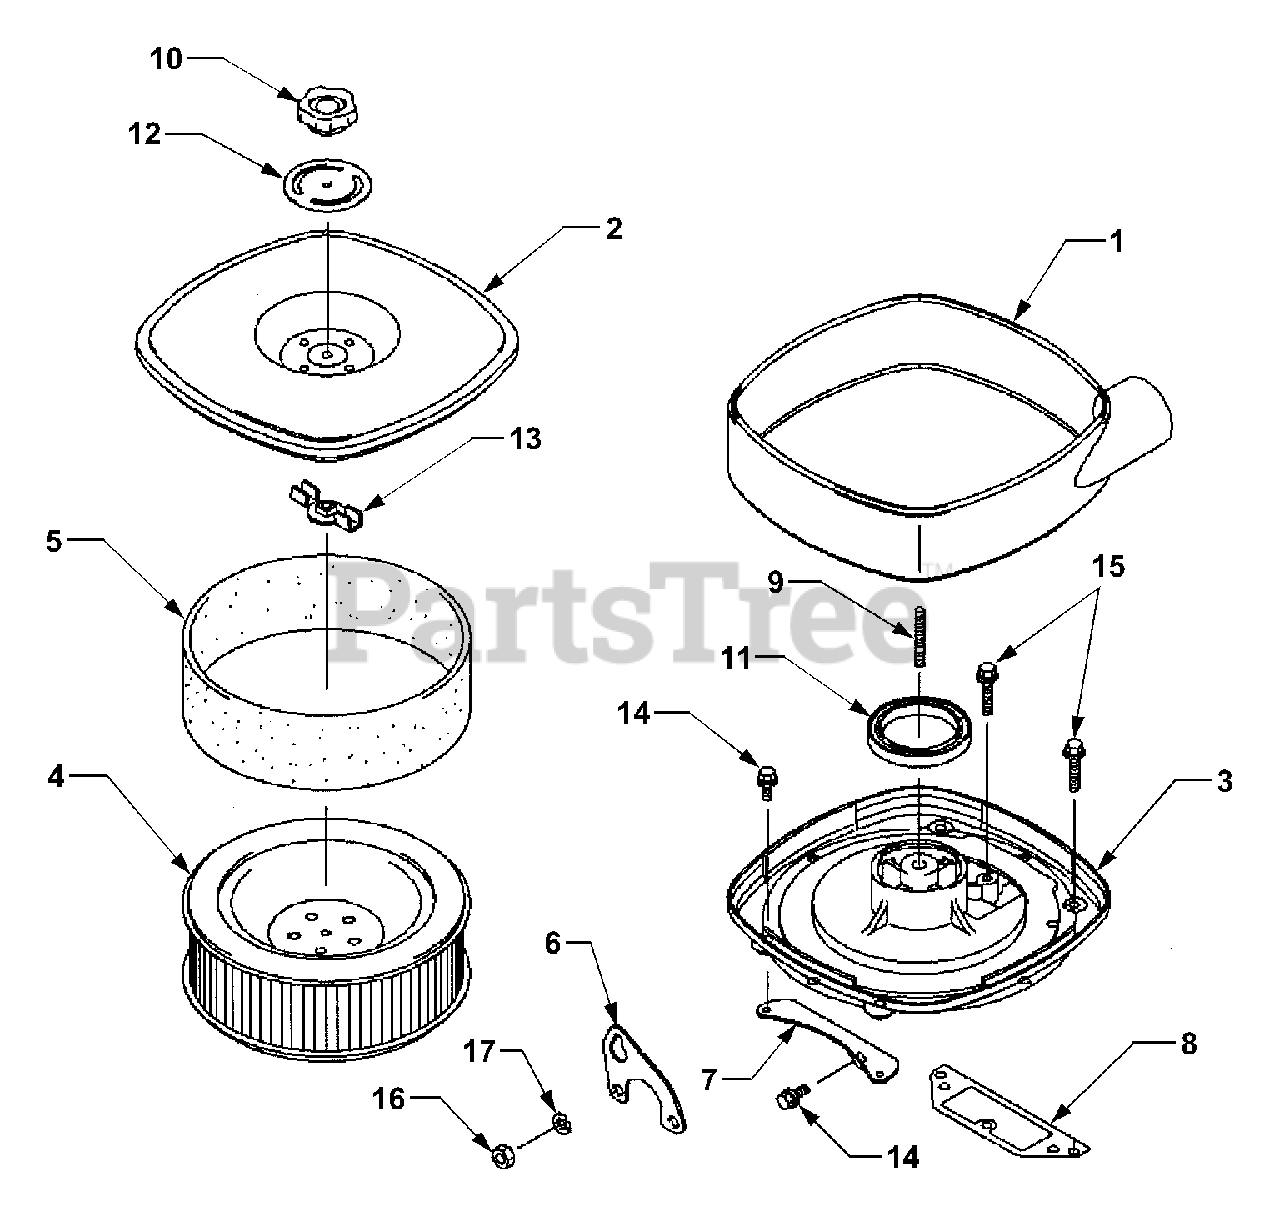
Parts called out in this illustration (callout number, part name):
1	Case, Air Filter Body
2	Case, Air Filter Upper
3	Case, Air Filter Lower
4	Element, Air Filter
5	Precleaner, Foam
7	Bracket, Air Filter
8	Gasket, Air Filter
11	Seal
14	Bolt, Flanged
15	Bolt, Flanged
17	Washer, Spring
